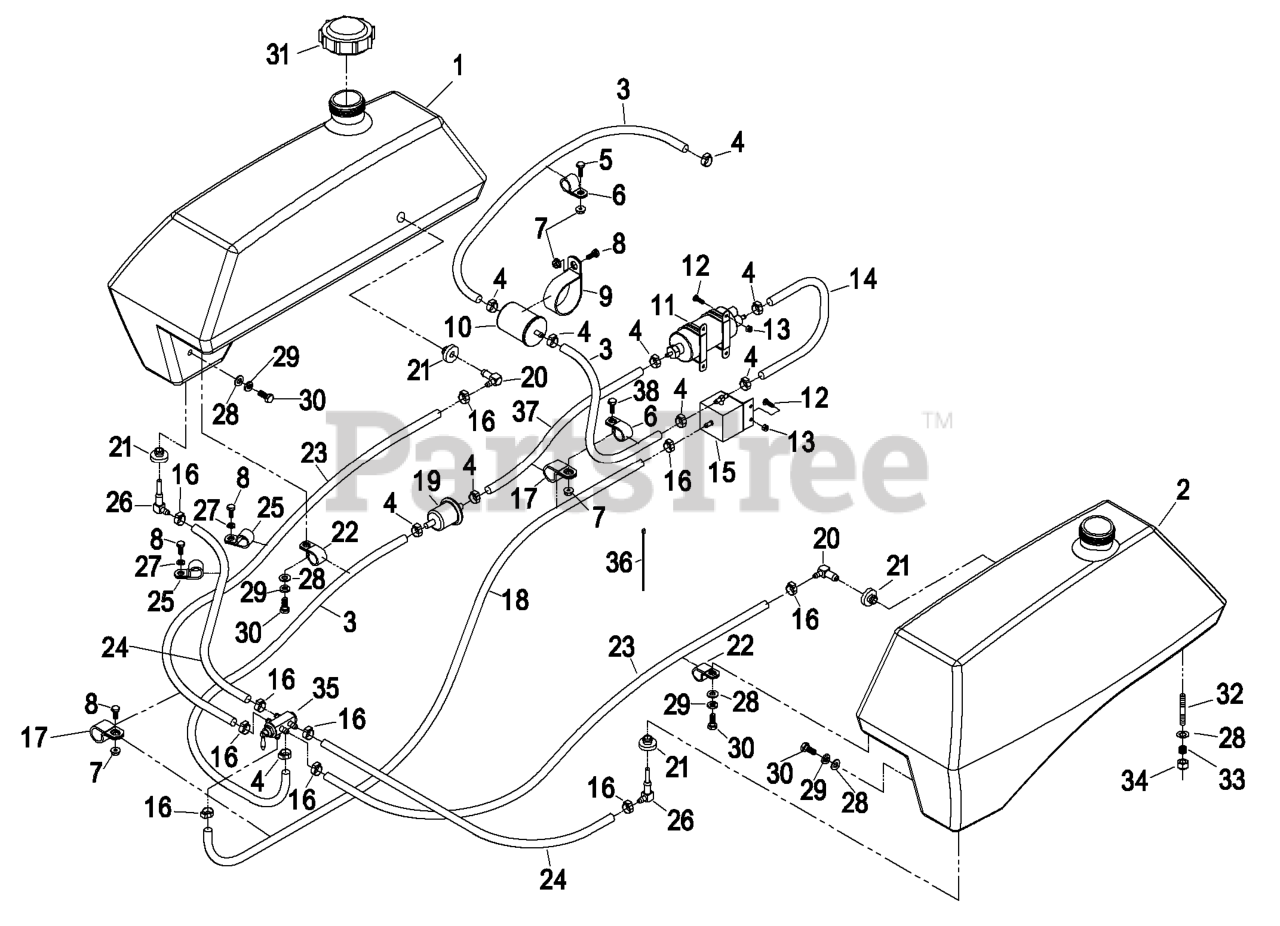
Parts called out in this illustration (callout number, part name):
4	CLAMP-HOSE, FUEL
5	SCREW-HH
6	CLIP-LOOM
8	SCREW-HH
9	CLIP-LOOM
10	Fuel Filter (Large)
11	Fuel Pump
12	SCREW-PPH
13	NUT-LOCK, NI
14	HOSE-FUEL
15	Fuel Regulator
16	CLAMP-HOSE, FUEL
17	CLIP-LOOM
20	ELBOW-90 DEG
24	HOSE-FUEL
25	CLIP-LOOM
26	ELBOW-TANK, FUEL
27	WASHER-LOCK
28	WASHER-PLAIN
29	WASHER-LOCK
30	SCREW-HH
31	CAP-FUEL
32	STUD
33	SPRING-TANK, FUEL
34	NUT-LOCK, NI
35	VALVE-FUEL, DUAL FLOW
36	TIE-CABLE
37	HOSE-FUEL
38	SCREW-HH
